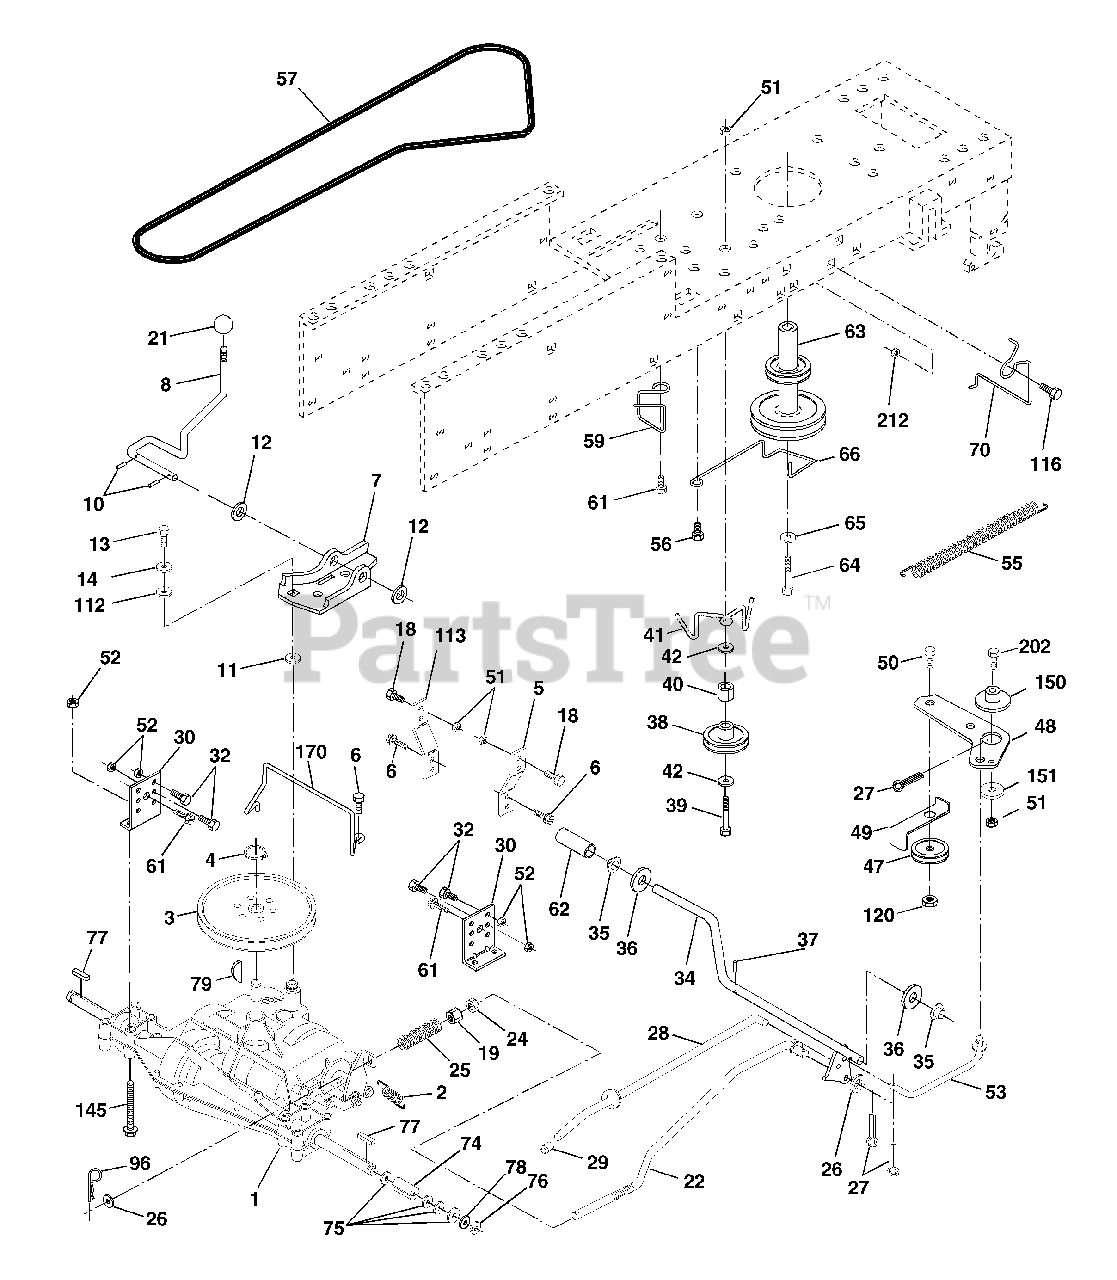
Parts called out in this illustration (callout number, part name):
2	Spring Return Brake
3	Pulley Transaxle 18"tires
4	Ring Retainer # 5100-62
5	Strap Torque 30 Degrees RH
6	Screw 5/16-18 x 3/4
7	Plate Rod Shift T/a
8	Rod Shifter Blk
10	Pin Cotter 1/8 X 1 Cad
11	Washer Plate Shf 388 Sq Hole
12	Washer 15/32 X 3/4 X 16 Ga
13	Bolt 1/4-28 unf Gr. 8 w/Patch
14	Washer Lock Hvy Helical 1/4
18	Bolt Fin Hex 3/8-16unc X 1 Gr. 5
19	Nut lock Hex w/Ins 3/8-16 Unc
21	Knob Rd 1/2-13 Plstc Thds Blk
22	Rod Brake LT
24	Nut Hex Jam 3/8-16 Unc
25	Spring Rod Brake 2 00 Zinc
26	Washer 13/32 X 13/16 X 16 Ga
27	Pin Cotter 1/8 X 3/4 Cad
28	Rod Brake Parking LT/YT
29	Cap Brake Parking Black
30	Bracket Transmission
32	Bolt Fin Hex 5/16-18 x 3/4
34	Shaft Asm Pedal Foot Nibbed
35	Bearing Nylon Blk 629 Id
36	Washer 21/32 X 1 X 16 Ga
37	Pin Roll 3/16 X 1"
38	Pulley Composite Flat
39	Bolt Fin Hex 3/8-16 x 3
40	Spacer Split 395 X 59 Bzp
41	Keeper Belt Idler
42	Washer 13/32 X 13/16 X 12 Ga
47	Pulley Idler V Groove Plastic
48	Bellcrank Clutch Grnd Drv STL
49	Retainer Belt Style Spring
50	Bolt Hex Hd 3/8-16unc X 1-1/2
51	Nut Crownlock 3/8-16 Unc
52	Nut Crownlock 5/16-18 unc
53	Link Clutch 7 66
55	Spring Return Clutch 6 75
56	Screw 3/8-16 x 1.0
57	V-Belt Ground Drive 95
59	Keeper Belt Chassis Span Ctr
61	Screw 3/8-16 x 3/4
62	Cover Pedal Blk Round
63	Engine Pulley LT/YT
64	Bolt Hex 7/16-20x4 Gr 5
65	Washer Lock Hvy Hlcl Spr 7/16
66	Keeper Belt Engine
70	Guide Belt Mower Drive RH
74	Spacer Axle
75	Washer 25/32 X 1 1/4 X 16 Ga
76	E-ring #5133-75
77	Key Square 2 0 X 1845/ 1865
78	Washer 25/32 X 1-5/8 X 16 Ga
79	Key Woodruff
96	Retainer Spring 1"
112	Washer 9/32 X 3/4 X 10 Ga
113	Strap Torque 90 Degrees LH
116	Bolt Rdhd Sq Neck 3/8-16 x 1
120	Nut Lock Flg 3/8-16
145	Bolt Hex Flg.Hd. 5/16-18 x Gr.5
150	Spacer Retainer Lt
151	Washer 13/32 x 2 x 10 Ga.
170	Keeper, Belt Transaxle Gear
202	Bolt Carr Sh 3/8-16 x 1-3/4 Gr.5
212	Nut Hex Flg Lock
